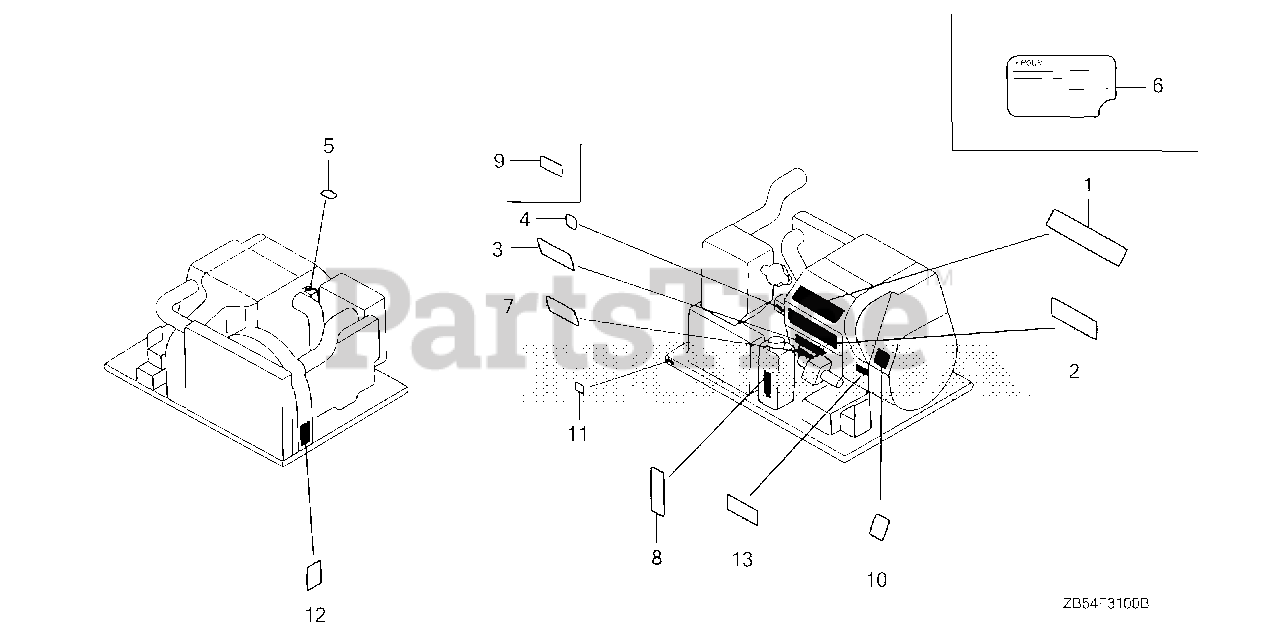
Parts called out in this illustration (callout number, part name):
2	EMBLEM (EVD4010)
3	LABEL, CONNECT WARNING (ENGLISH)
4	PLATE, INTERVAL (ENGLISH)
5	PLATE, AIR CLEANER WARNING (ENGLISH)
6	LABEL, REMOTE OPENER (FRENCH)
7	PLATE, WARNING (ENGLISH)
8	MARK, COOLANT INDICATION (ENGLISH/FRENCH)
10	MARK, OIL CAUTION
11	MARK, GRAND
